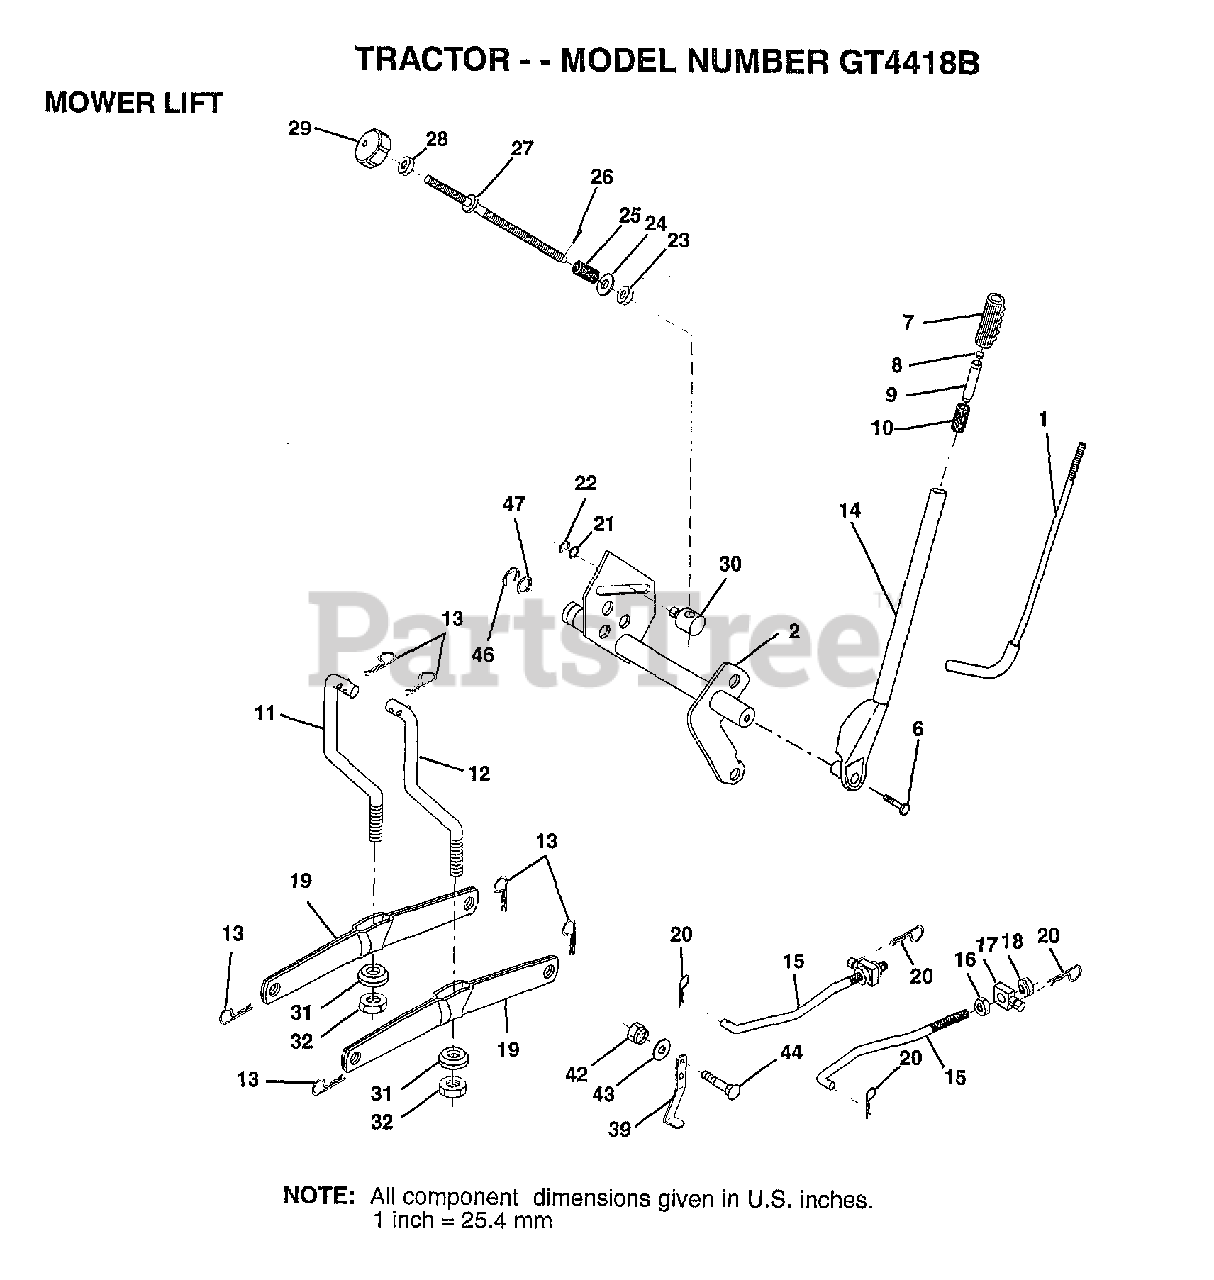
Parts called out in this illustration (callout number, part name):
1	LEVER ROD LT
2	SHAFT LIFT W/IND
6	"BOLT,HEX"
7	GRIP
10	SPRING T
11	LINK.LIFT.LH.GTV
12	LINK.LIFT.RH.GTV.
15	LINK.FRONT
16	NUT
17	TRUNION
18	NUT.LK.W/WSH.1/2.
19	ARM SUSP REAR
20	RETAINER.SPRING
21	WASHER
22	KLIP RING
23	NUT T
24	WASHER
25	SPRING T
27	ROD LIFT LT
28	NUT
29	KNOB INF 3/8-16
30	TRUNION LT
31	BEARING PVT LH
32	NUT.LOCK.3/8-24
39	STOP.OVER.CENTER
43	WASHER GT
44	BOLT
46	E-RING
47	WASHER
